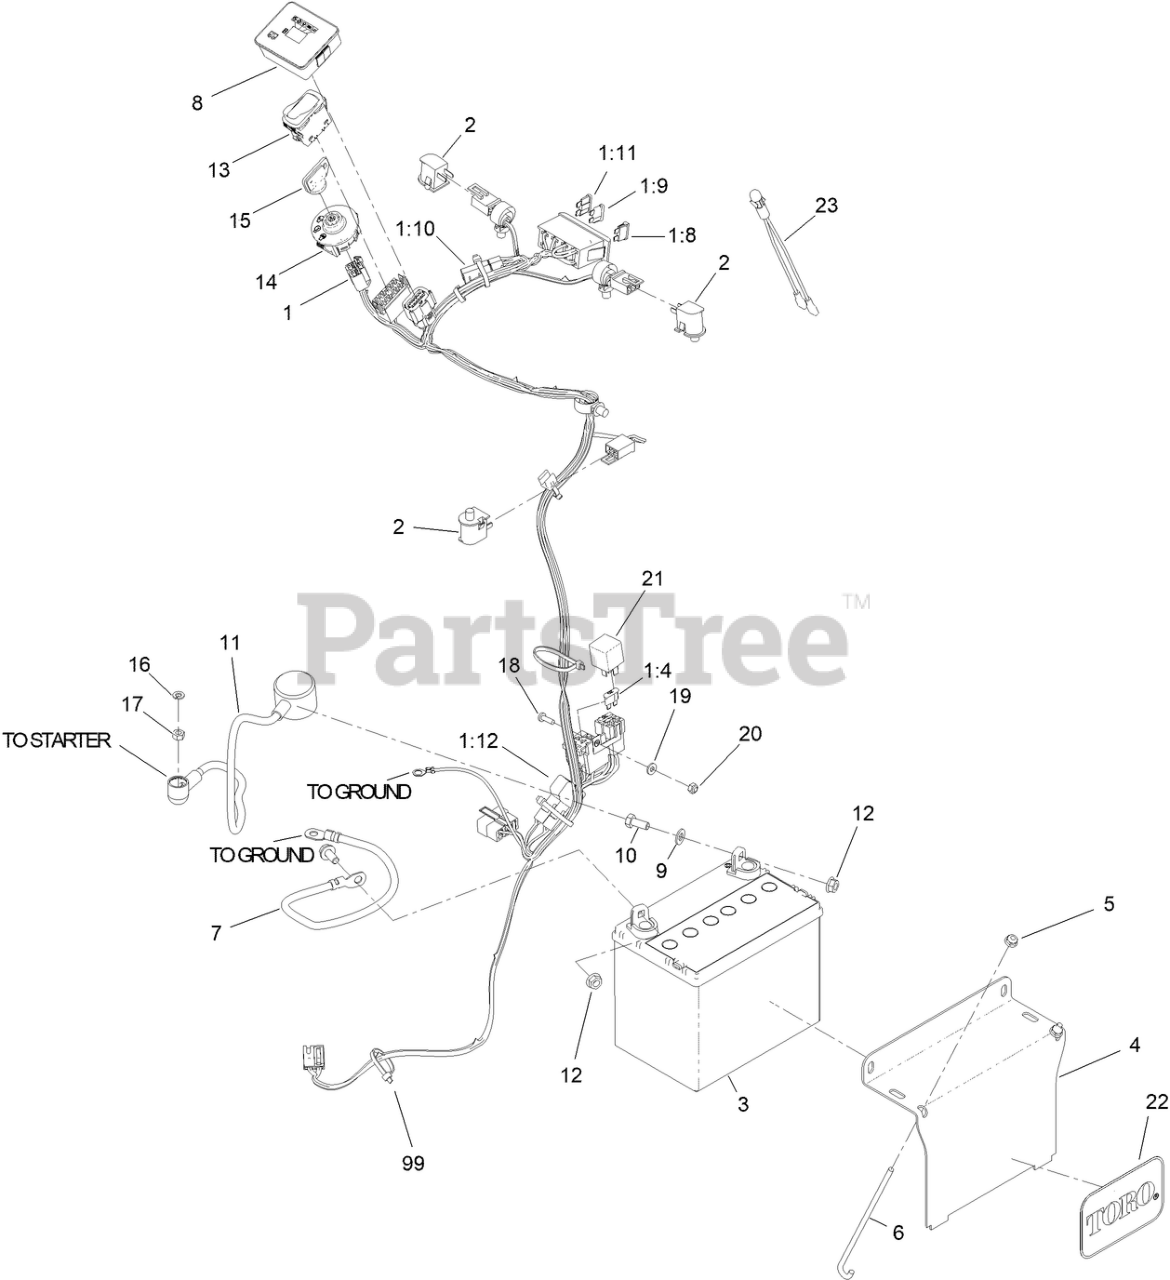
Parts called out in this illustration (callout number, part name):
1	HARNESS-WIRE, GRANDSTAND
1:4	FUSE-BLADE, 20 AMP
1:8	FUSE-BLADE, 15 AMP
1:9	FUSE-BLADE, 10 AMP
1:10	CAP-PLUG
1:11	FUSE-BLADE, 5 AMP
2	SWITCH-BAIL
3	BATTERY-DRY
4	BRACKET-HOLD DOWN, BATTERY
5	NUT-HF
6	BOLT-HOLDDOWN
7	CABLE-BATTERY, BLACK
8	MODULE-METER, HOUR
9	WASHER-PLAIN
10	SCREW-HH
11	CABLE-BATTERY, POSITIVE
12	NUT-HHF, SMOOTH
13	SWITCH-ROCKER, (ON)-ON-OFF
14	SWITCH-IGNITION
15	KEY-IGNITION
16	WASHER-LOCK
17	NUT-HEX
18	SCREW-PPH
19	WASHER-FLAT
20	NUT-LOCK, NI
22	DECAL
23	INDICATOR-LED, RED
99	TIE-CABLE
